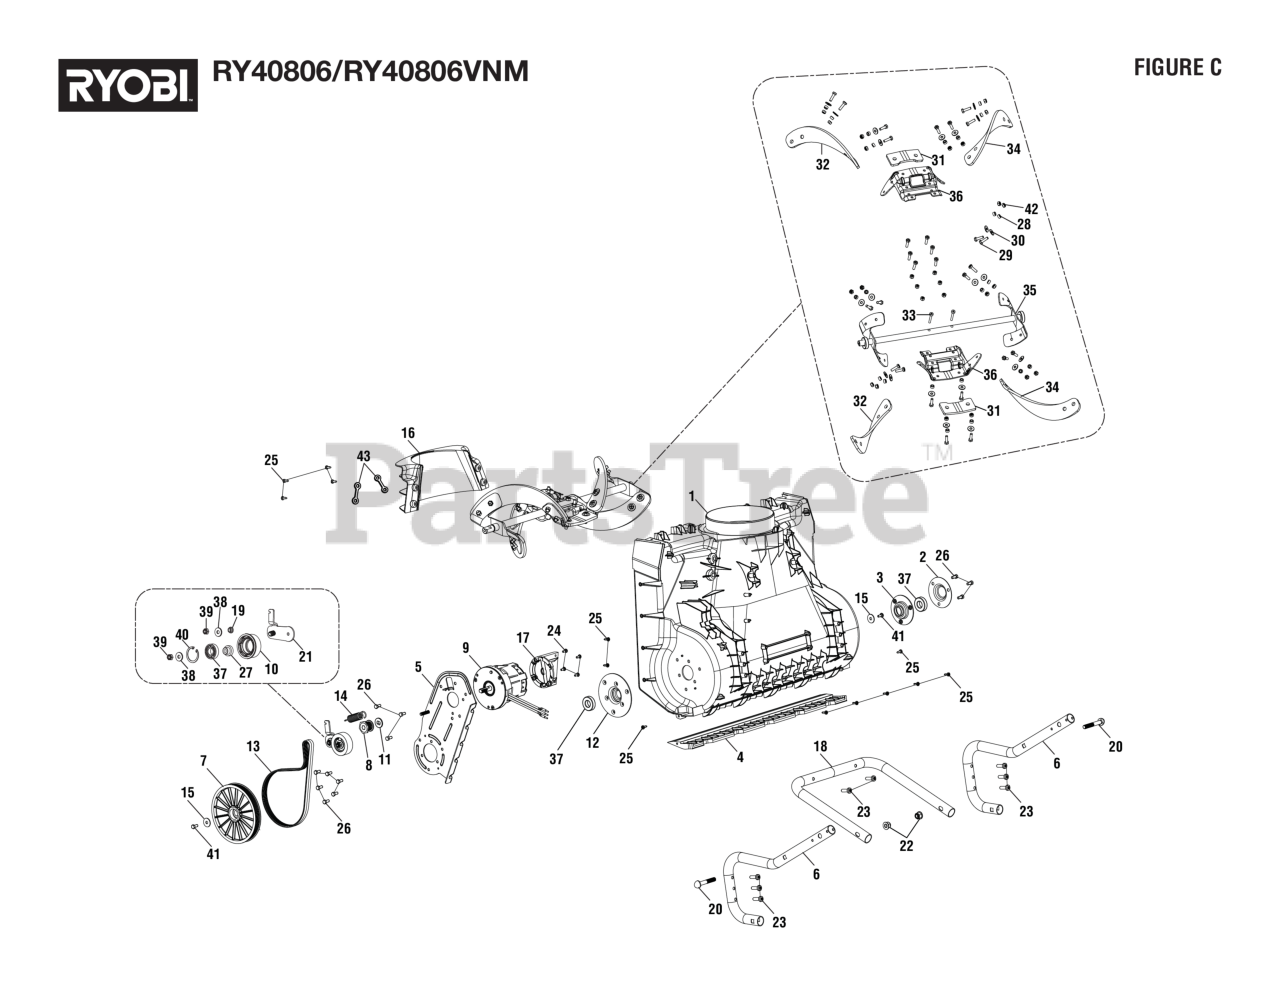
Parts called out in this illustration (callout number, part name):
1	Lower Housing
2	Cover Plate
3	Bearing Retainer
4	Scraper Blade
5	Motor Mounting Plate
6	Housing Mount Tube
7	Auger Pulley
8	Motor Pulley
10	Idler Pulley
12	Bearing Retainer Plate
14	Belt Tensioner Spring
15	Flat Washer, ID6.6XOD20XT1.6, 65Mn,
16	Lower Chute Neck
17	Mount Assembly
18	Bracing Bar
19	Flange Washer
20	Bolt (M8 x 60 mm, Pan Hd.)
21	Idler Bracket
22	Flange Lock Nut (M8 x 1.25 mm)
23	Screw (1/4-15 x 3/4 in., T30 Torx Pan Hd.)
24	Screw, M4X0.7, SCM435, Black Zinc Plated
25	Screw (M4.2 x 12 mm, T20 Torx Pan Hd.)
26	Screw (M5 x 12 mm, Hex Hd.)
27	Spacer (Idler Bracket)
28	Auger Paddle Spacer
29	Bolt (M6 x 16 mm, Hex Soc. Hd.)
30	Washer (OD18 x ID6.6 x 1.5t)
31	Auger Paddle (Center)
32	Auger Paddle (Drive Side)
33	Screw (M5 x 30 mm, T25 Torx Pan Hd.)
34	Auger Paddle (Long Side)
35	Flange and Shaft Assembly
36	Center Bracket.
37	Ball Bearing (6002 2RS)
38	Washer (OD18.8 x ID7 x 2t)
39	Nut (#1/4-20)
41	Screw (M6 x 12 mm, T27 Torx Pan Hd.)
42	Lock Nut (M6)
43	Terminal Block Holder
